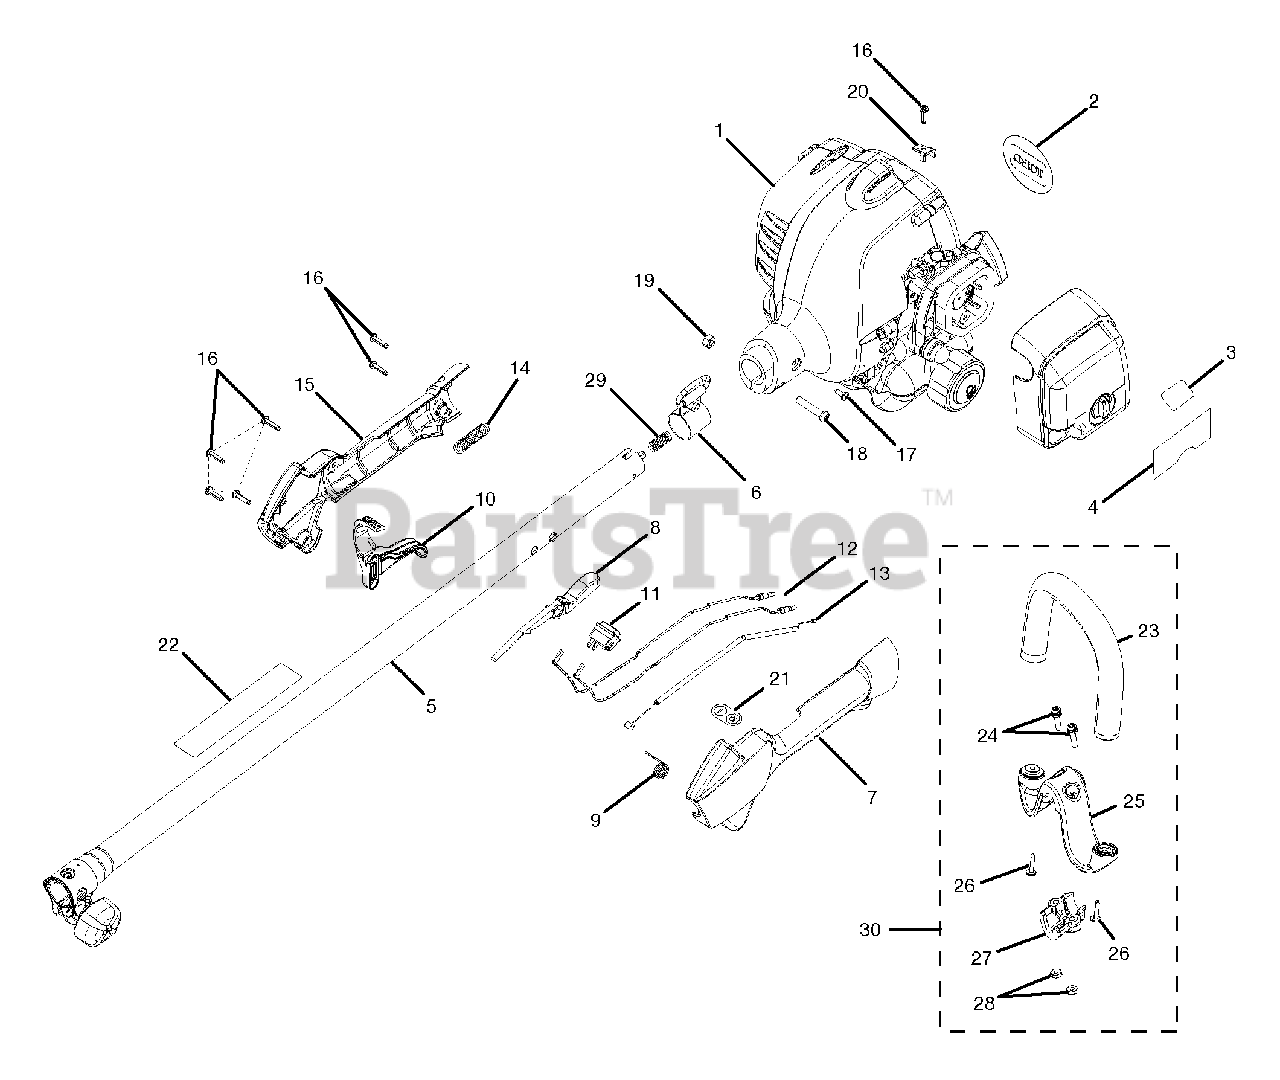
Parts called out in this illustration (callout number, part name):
1	Engine Assembly
2	Logo Label
3	Upper Start Label
4	Lower Start Label
5	Upper Shaft Assembly
6	Hanger Bracket
7	Rear Handle Support
8	Lock-off Button
9	Trigger Spring
11	Switch with Dust Shield
13	Cable, throttle
14	Corrugated Tube
15	Rear Handle Cover
16	Screw (M4x 1.75 x 16 mm)
17	Screw (#8-16 x1/2 in., Trilobular)
18	Screw (M6x 1 x 30 mm)
19	Hex Nut
20	Retaining Ring
21	On/Off Label
22	Warning Label
23	Assist Handle w/grip
24	12-24 x 1 SEMS
25	M Clamp
26	Slotted Torx Screw
28	12 - 24 Hexnut
29	Spring, Shaft
30	Assist Handle
